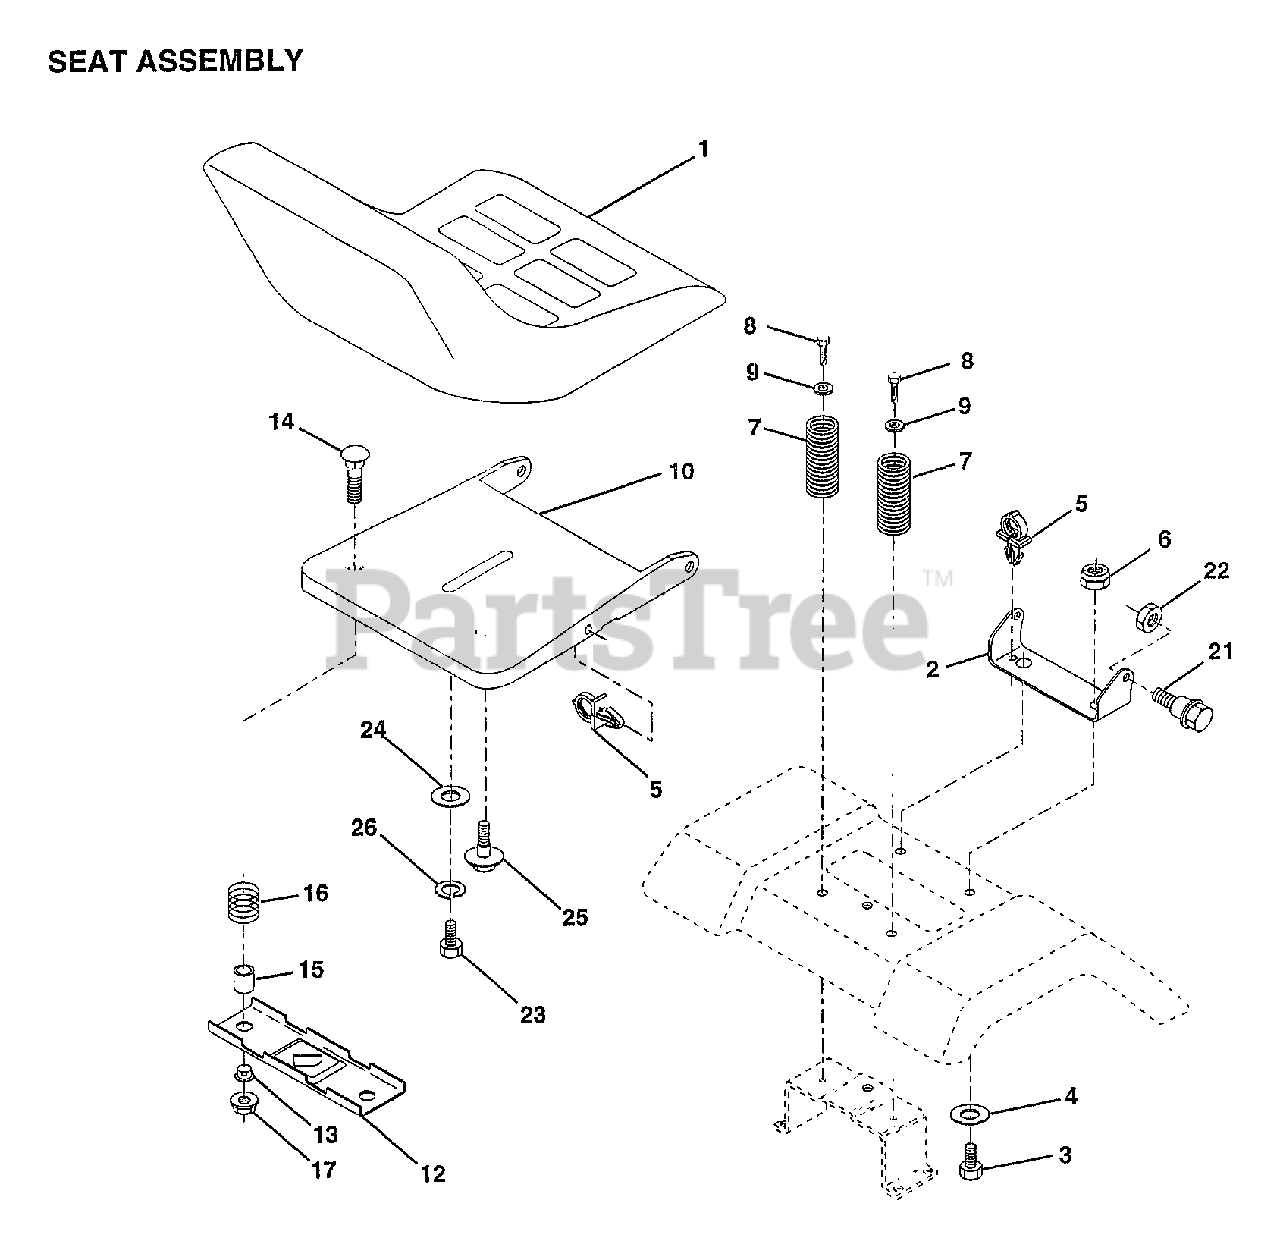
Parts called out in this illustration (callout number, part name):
2	BRACKET PVT SEAT
3	BOLT
4	WASHER PM
5	CLIP.PUSH-IN.HING
6	NUT
7	SPRING COMPRESSIO
8	SCREW GTV
9	WASHER
10	PAN-SEAT
12	BRKT SWITCH
13	BUSHING
14	BOLT-RD HD SQ NK
15	SPLIT SPACER
16	SPRING
21	"BOLT,SHOULDER"
22	NUT
23	BOLT
24	WASHER
25	"BOLT,SHOULDER"
26	LOCKWASHER
